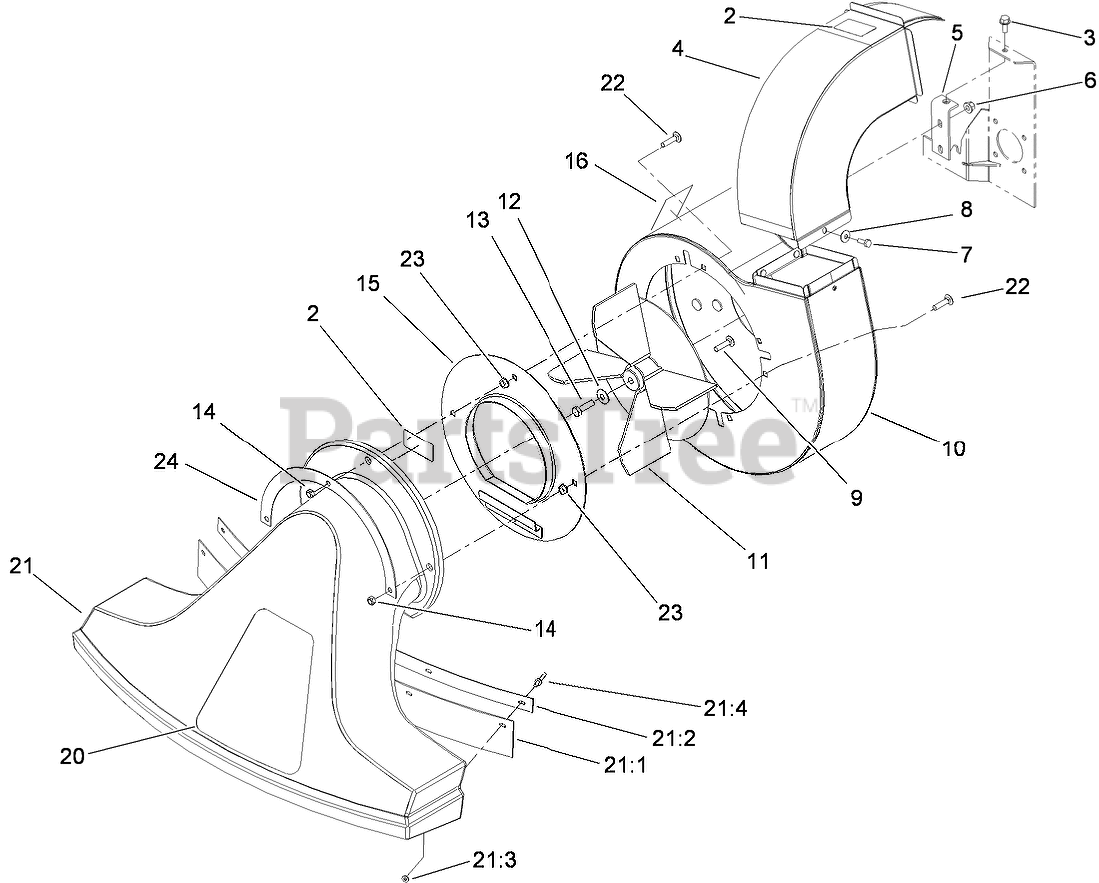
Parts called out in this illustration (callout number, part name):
2	DECAL-CAUTION, BAG
3	SCREW-HWHTF
4	VACUUM CHUTE ASM
5	BRACKET-MOUNTING, HOUSING
6	NUT-HF, NI
7	SCREW-HH
8	WASHER-BELLEVILLE
9	SCREW-CARR
10	BLOWER/VAC HOUSING ASM
11	FAN ASM
12	WASHER-BELLEVILLE
13	SCREW-HH
14	NUT-LOCK, NI
15	COVER-BLOWER
16	DECAL-WARNING, ROTATE
21	SNOUT ASM
21:1	FLAP-RUBBER
21:2	CLAMP-FLAP
21:3	WASHER-FLAT
21:4	RIVET-POP
22	SCREW-CARR
23	NUT-HF
24	Flange-Retainer
